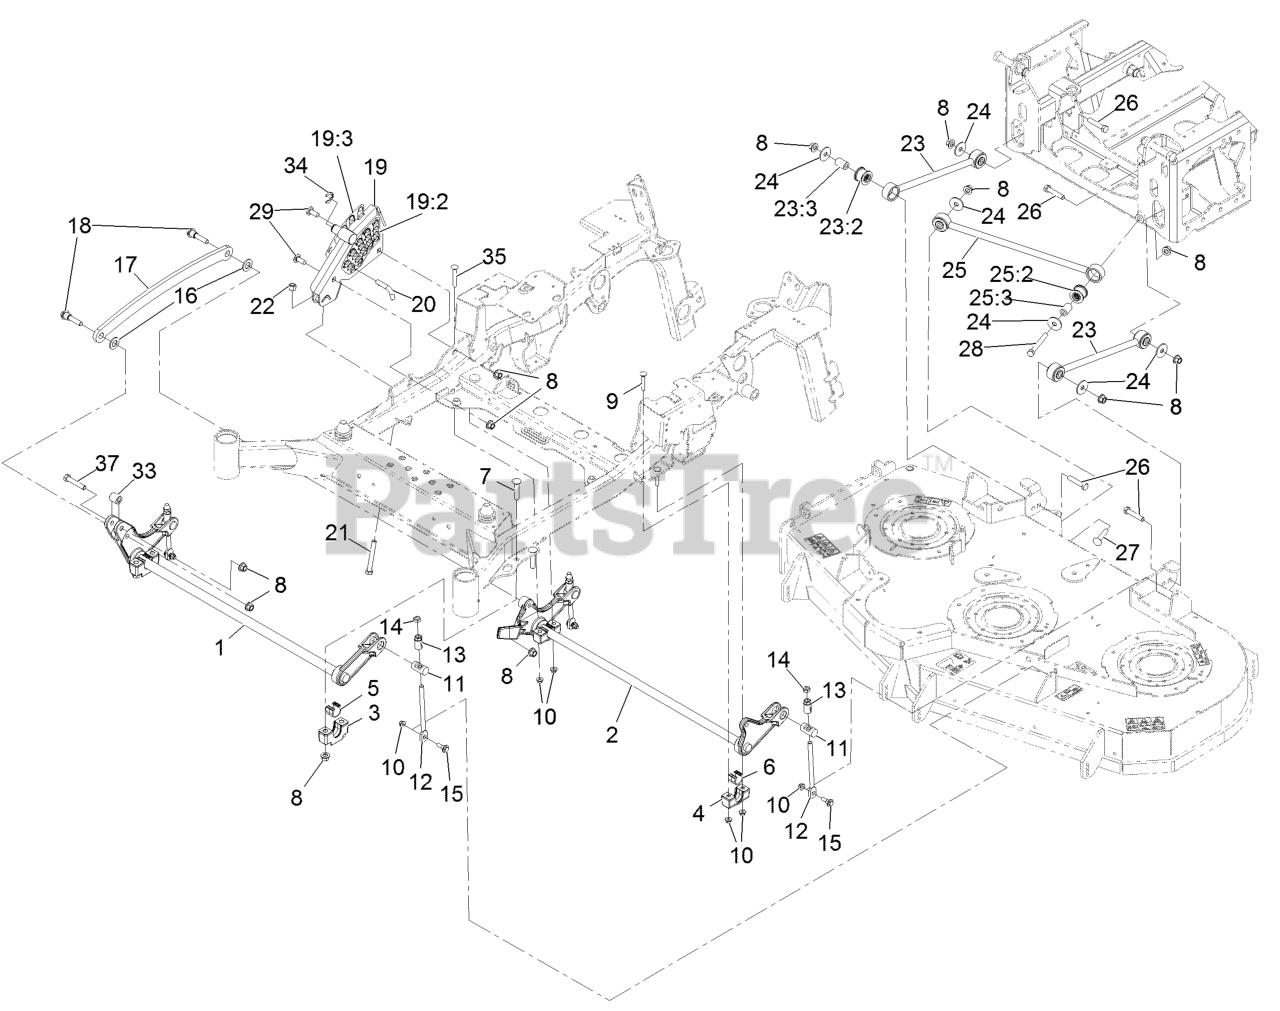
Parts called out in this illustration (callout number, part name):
1	Decklift-Front
2	Lift-Deck, Rear
3	Support-Cross Shaft, Bearing
4	Support-Cross Shaft, Bearing Rear
5	Bearing-Cross Shaft, Front
6	Bearing-Cross Shaft, Rear
7	Bolt-Carriage 1/2-13 X 2 1/2 Spl Neck
8	Nut-Lock 1/2-13
9	Bolt-Carriage 3/8-16 X 2 1/4
10	Nut-Nyloc 3/8-16 Flg
11	Trunnion
12	Link-Adjuster, Deck Lift
13	Adjuster-Lift, Deck
14	Nut-Jam 1/2-13
15	Screw-Hex Flange 3/8-16 X .80
16	Washer-3/4 SAE
17	Link-Lift, Deck
18	Screw-Hex Flange 1/2-13 X 1.90
19	HOC ASM
19:2	Decal-Height Of Cut
19:3	Decal-Height Of Cut, Outer
20	Pin-HOC
21	Bolt-HH 1/2-13 X 4 Tap
22	Nut-Nyloc 1/2-13
23	Deck Strut ASM
23:2	Bushing-Suspension, Rubber
25	Panhard Rod ASM
25:2	Bushing-Suspension, Rubber
26	Screw-HH 1/2-13 X 2 1/2
27	Bolt-Carriage 1/2-13 X 2 1/2
28	Screw-HH 1/2-13 X 4
29	Screw-CARR, Short Neck
33	Spacer-Pivot
34	Ring-Retaining
35	Bolt-Carriage 3/8-16 X 2 3/4
37	Screw-HH 1/2-13 X 2 3/4
